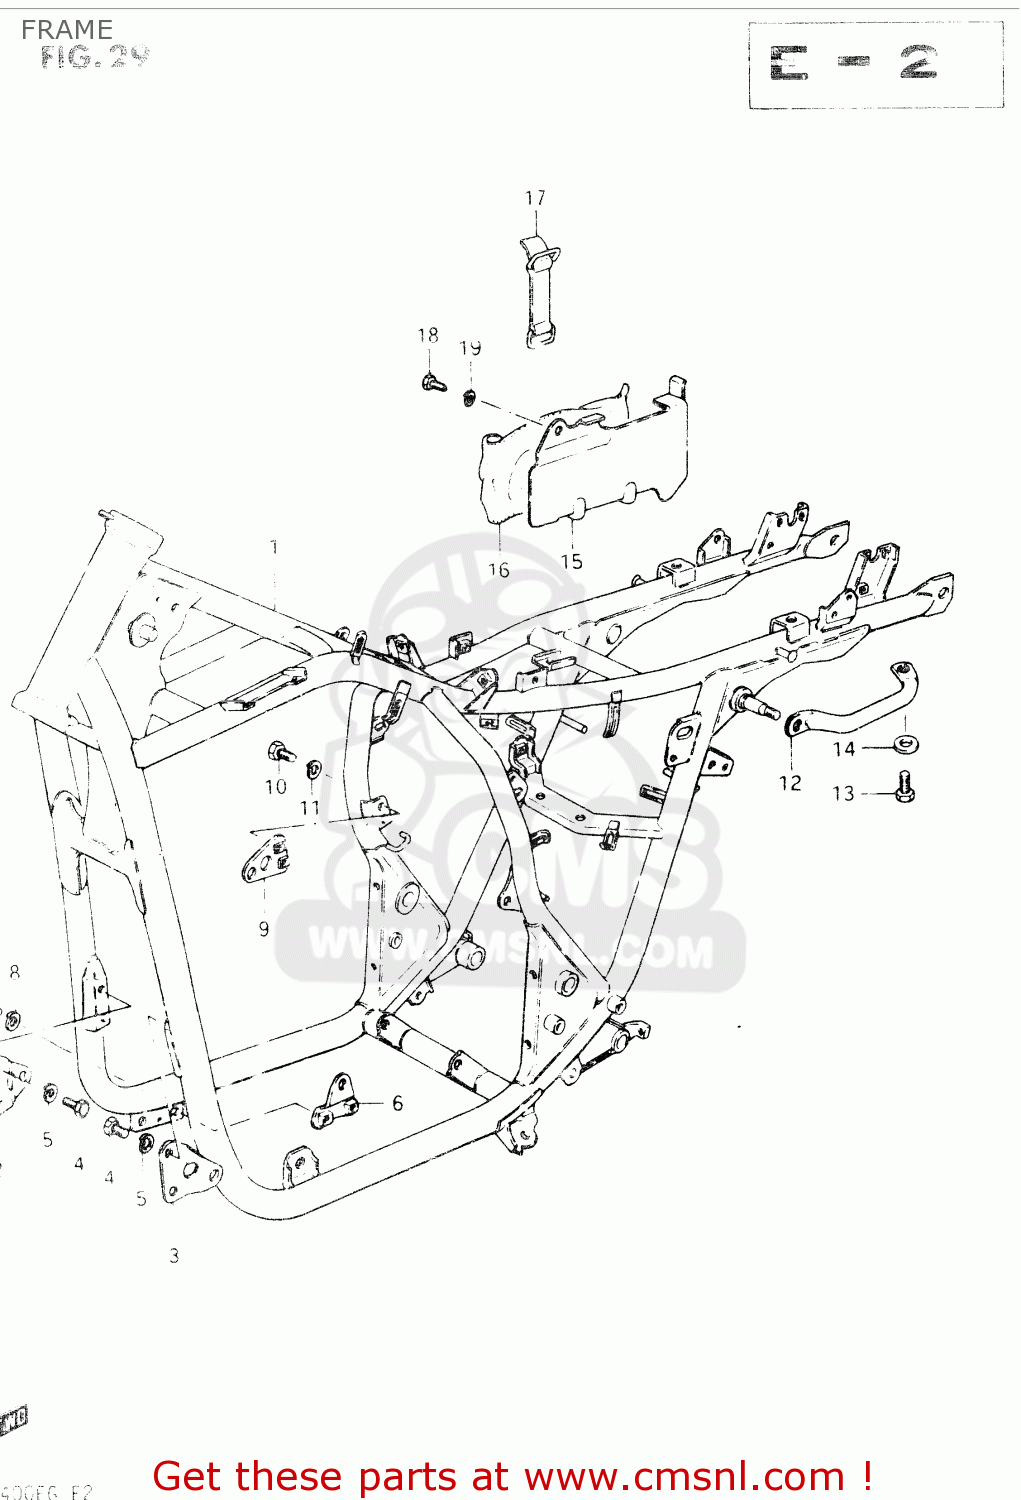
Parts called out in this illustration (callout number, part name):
1	FRAME (BLACK)
2	PLATE,ENG MTG NO.1,R
3	PLATE,ENGINE MOUNTING,LEFT
4	BOLT
5	WASHER,LOCK,8.
6	PLATE,MOUNTING NO.2,LEFT
7	BOLT
8	WASHER,LOCK,8.
9	PLATE,MOUNTING NO.4,LEFT
10	BOLT
11	WASHER,LOCK,8.
12	GRIP,FRAME HANDLE
13	BOLT
14	WASHER
15	HOLDER,TOOL
16	TOOL SET
17	BAND
18	BOLT
19	WASHER,LOCK
